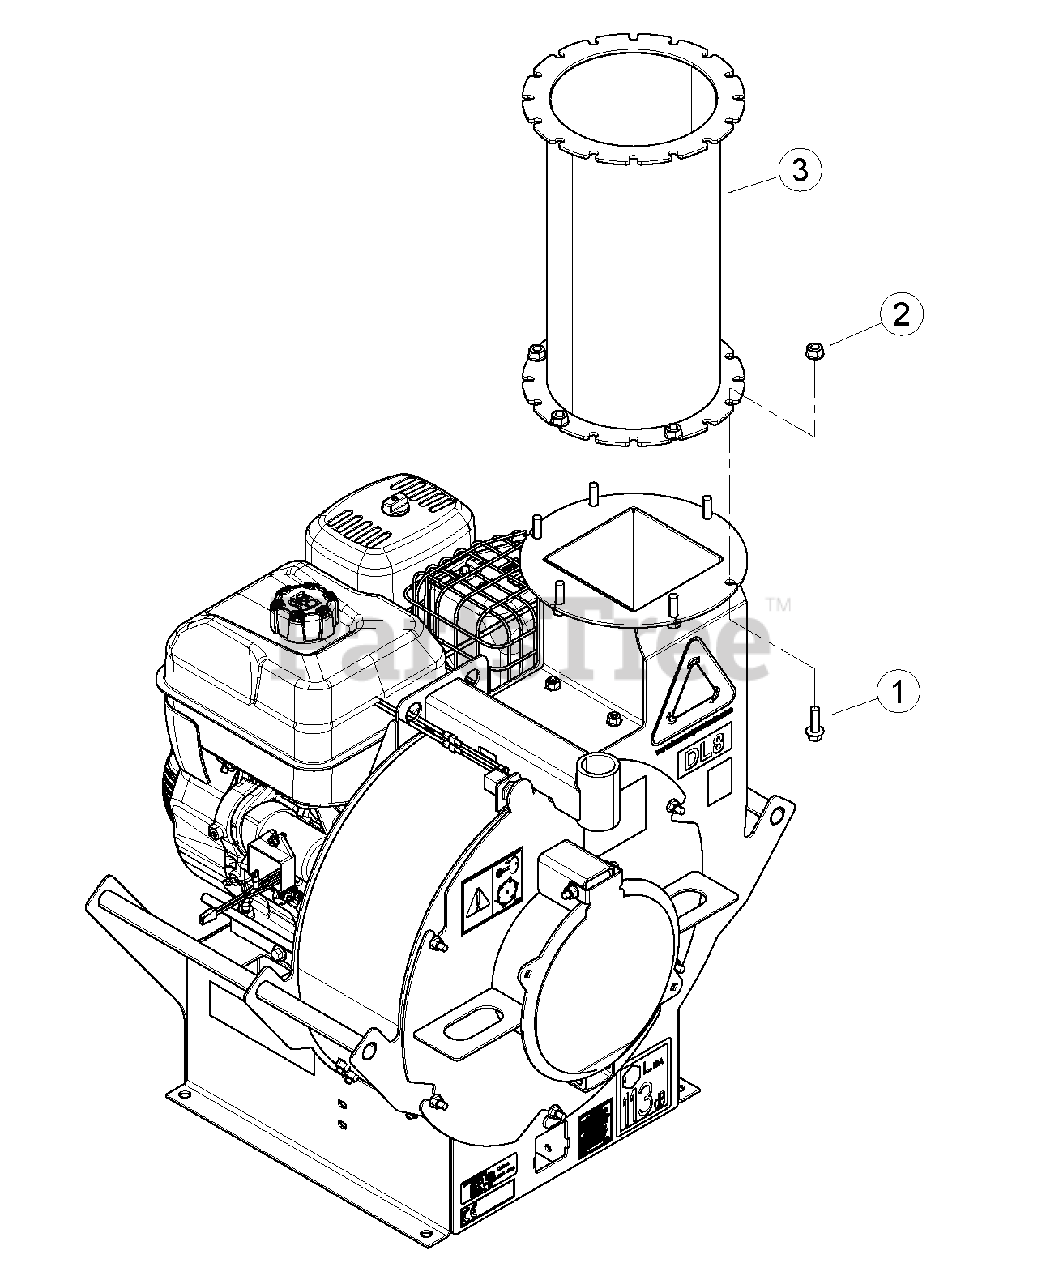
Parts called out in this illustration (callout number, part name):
1	BOLT, 3/8 X 1-1/4 FLANGE NC
2	NUT, 3/8-16 NYLOCK FLANGE
3	WELDMENT, CHUTE EXTENSION
